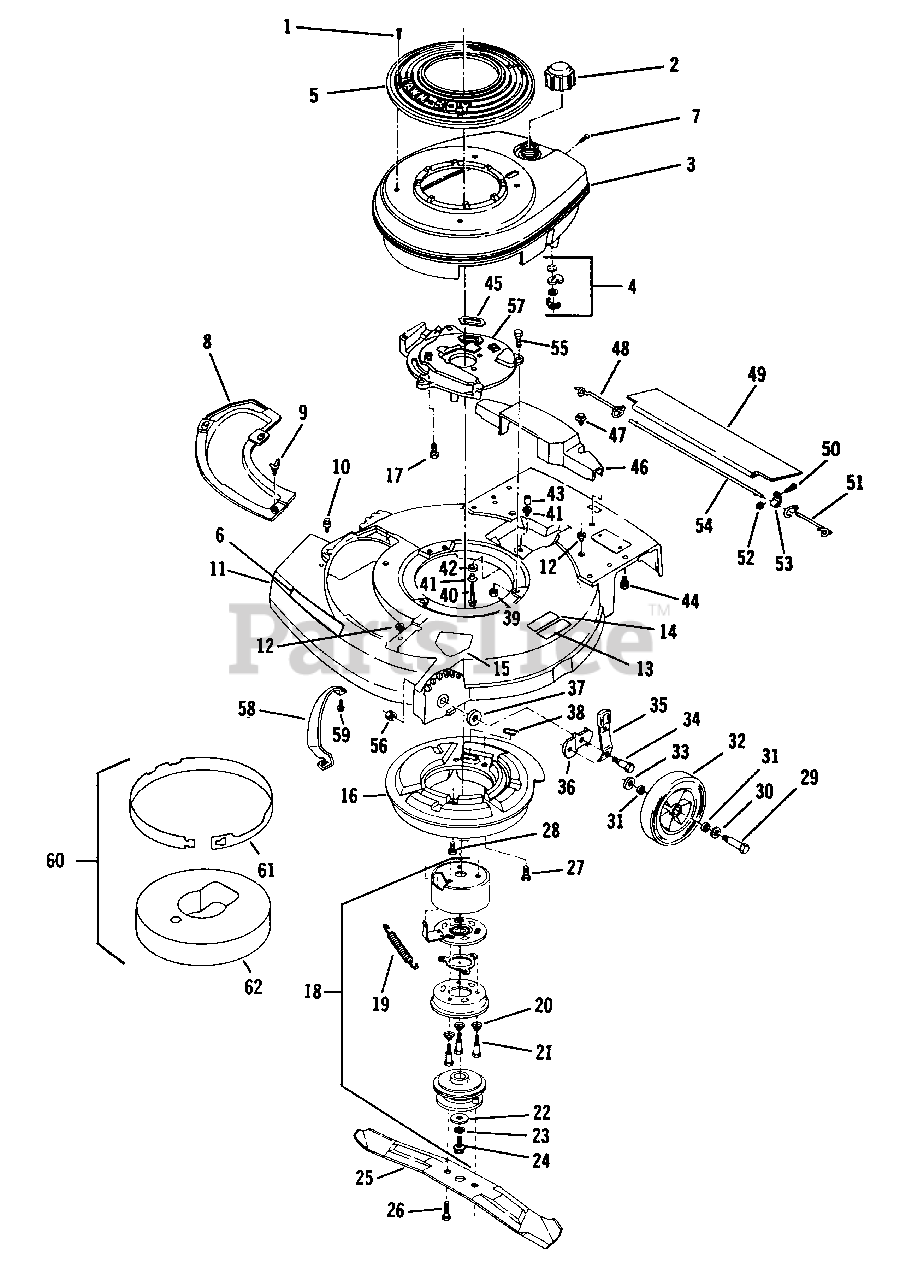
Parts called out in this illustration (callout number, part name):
1	Screw
3	Shroud-Engine
4	Fuel Shut-Off Assembly
5	Cover-Shroud
6	Decal-Clutch
7	Screw-Shroud to C.D. Brk't.
8	Cover Plate
9	Wing Screw
10	Screw-Plate and Chute Mounting
11	Housing Assembly
12	Grommet
13	Starting Pad
14	Decal-Starting Pad
15	Decal-Blade Contact Warning
16	Muffler Assembly
17	Screw-Eng. Mtg. Plt. to Blk.
18	Clutch Brake Assembly
19	Spring
20	Spring-Pressure
21	Screw-Shoulder
22	Washer
23	Lockwasher
24	Screw-Socket Head
25	Blade-21"
26	Screw-Sems-Blade
27	Screw-Muff. to Block
28	Screw-Muff. to Engine Mounting Plate
29	Bolt-Wheel-Front Washer
30	Washer
31	Washer-Felt
32	Wheel-Front
33	Washer
34	Shoulder Bolt
35	Knob and Spring Assembly
36	Bracket-Wheel Hgt. Adj.
37	Washer
38	Seal-Exhaust
39	Nut-Eng. Mtg. Plt. to Hsg.
40	Screw
41	Spacer
42	Grommet
43	Spacer
44	Screw-Handle Bracket
45	Gasket Exhaust
46	Cover-Drive Axle
47	Screw-Axle Cover Mtg.
48	Spring-R.H.
49	Shield-Trailing
50	Screw
51	Spring-L.H.
52	Nut
53	Clamp
54	Rod-Trailing Shield
55	Screw-Eng. Mtg. Plt.
56	Nut
57	Plate-Eng. Mtg.
58	Toe Bar
59	Screw
60	Muffler Seal and Shield Kit
61	Shield-Muffler Seal
62	Seal-Muffler
